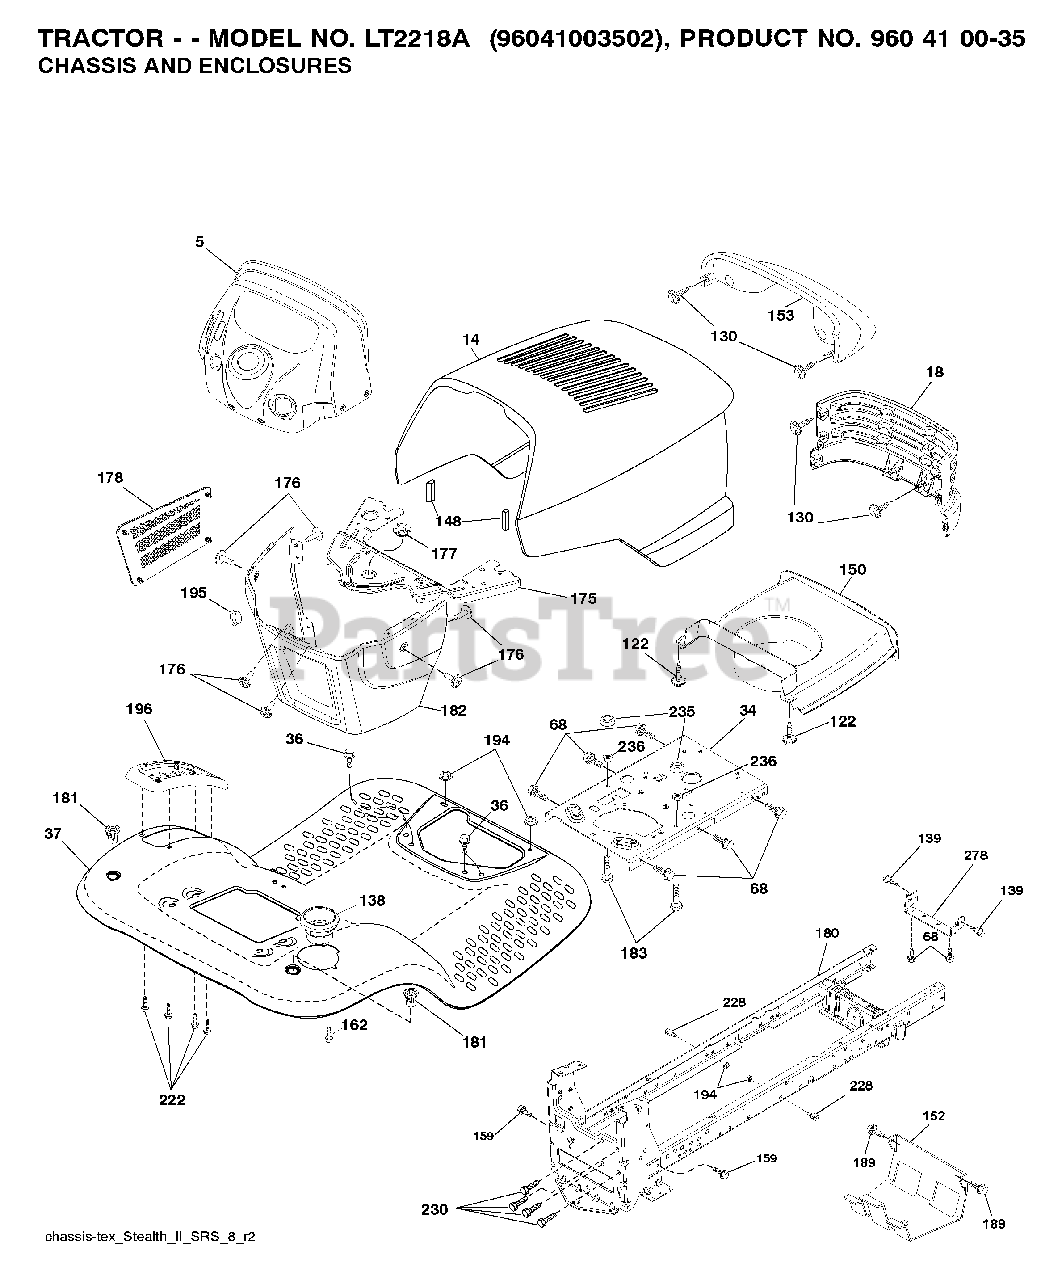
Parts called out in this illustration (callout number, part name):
34	PLATE.ENGINE.WELDED.CHASSIS
36	SCREW 5/16"
122	SCREW.WSHD.HEX10-32X5/8
130	SCREW
138	CUPHOLDER.TL.TEX.BLACK
139	BOLT, SHOULDER 5/16-18
148	EXTRUSION BUMPER
150	DUCT HOOD
152	SHIELD BROWNING
159	SCREW, 3/8-16X3/4
162	SCREW.HI-LO.CONSOLE
175	CROSSMEMBER.
176	SCREW.#10-24X5/8.RN.QU
177	BUSHING,STEERING
178	CARGO.ASM.NET.DASH.LOWER
180	CHASSIS
181	FEND/FTRST.PCH.CPH.NFW
182	DASH.LOWER.
183	BOLT.5/16-18X1-1/4 FULL.THREAD
189	SCREW
194	NUT LOCK HEX FLANGE 5/16-18
195	PLUG.HOLE.DASH.LOWER.12V.BLK
196	CONSOLE.ASM.DECK.LIFT.TLT.BLAC
222	SCREW.1/4-20X5/8
228	STUD.FASTNER.W/ANTI-ROTATE
230	SHOULDER BOLT 5/16-18TT
235	SPACER FENDER
236	NUT.CENTERLOCK.5/16-
278	BRKT.HOOD/MUFF.STEALTH
